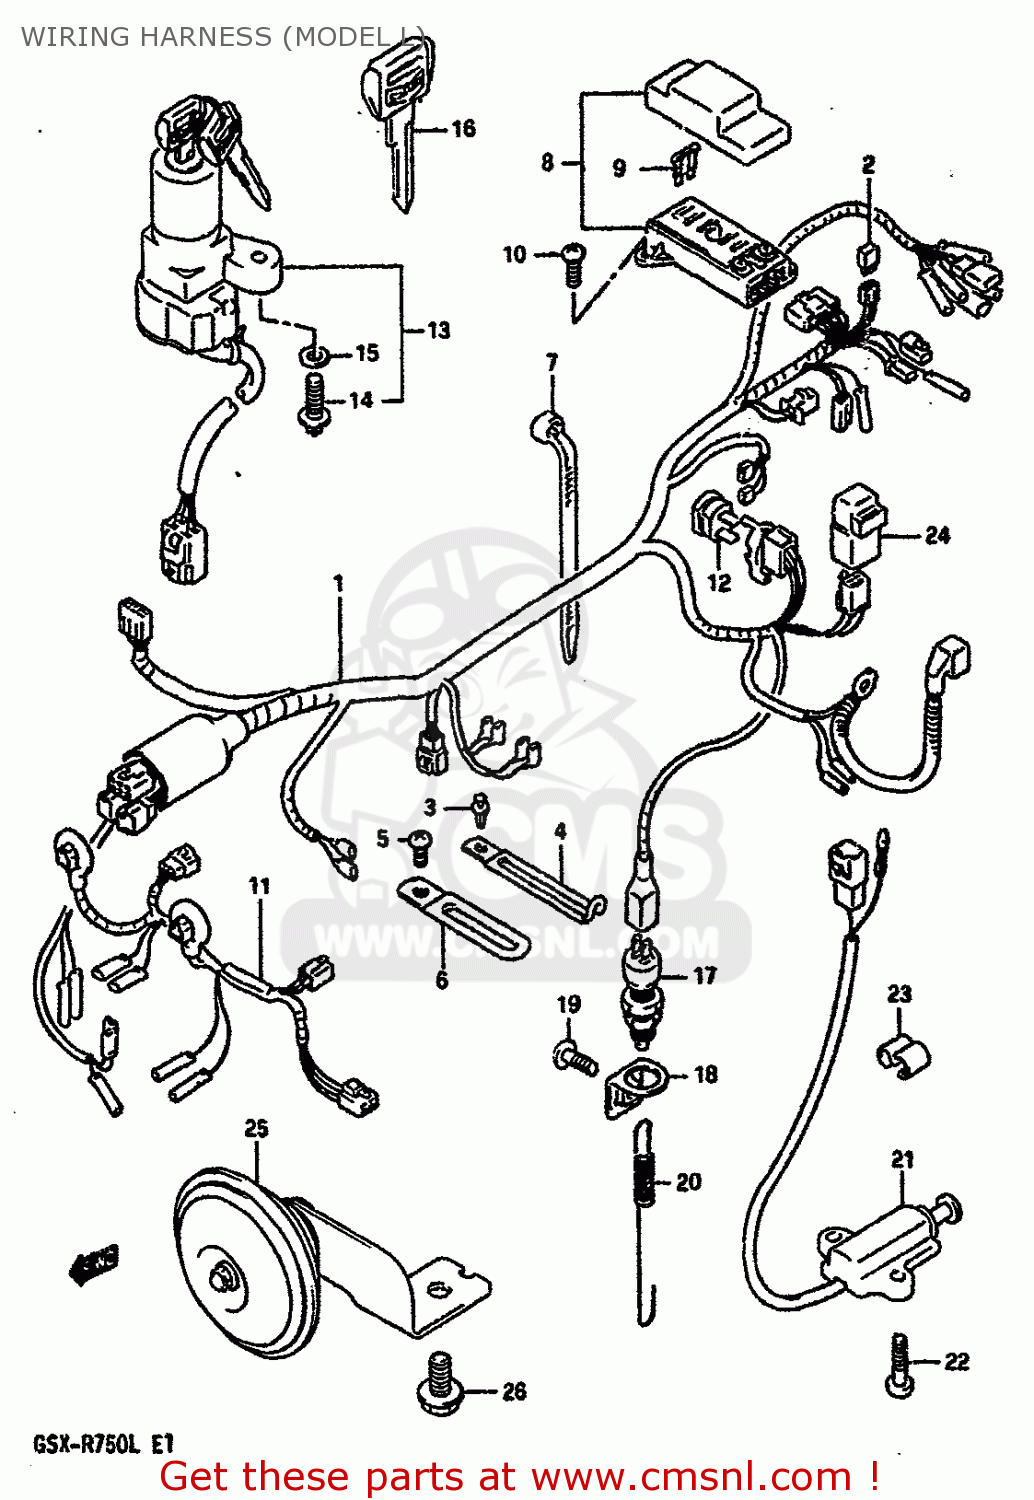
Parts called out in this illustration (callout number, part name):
1	HARNESS,WIRING
2	DIODE(STANLEY DE8804)
3	CLIP
4	CLAMP
5	SCREW
6	CLAMP
7	CLAMP(L:125)
8	BOX ASSY,FUSE
9	FUSE(10A)
10	SCREW
11	WIRE,HEADLAMP LEAD
12	BREAKER ASSY,CIRCUT
13	LOCK ASSEMBLY,STEERING
14	SCREW(6X18)
15	WASHER
16	KEY,BLANK
17	SWITCH ASSY,STOP LAMP
18	BRACKET,STOP LAMP SWITCH
19	SCREW(6X12)
20	SPRING
21	SWITCH ASSEMBLY,SIDE STAND
22	SCREW
23	CLIP
24	RELAY ASSEMBLY
25	HORN ASSEMBLY
26	BOLT 8X12
31	KEY,BLANK
